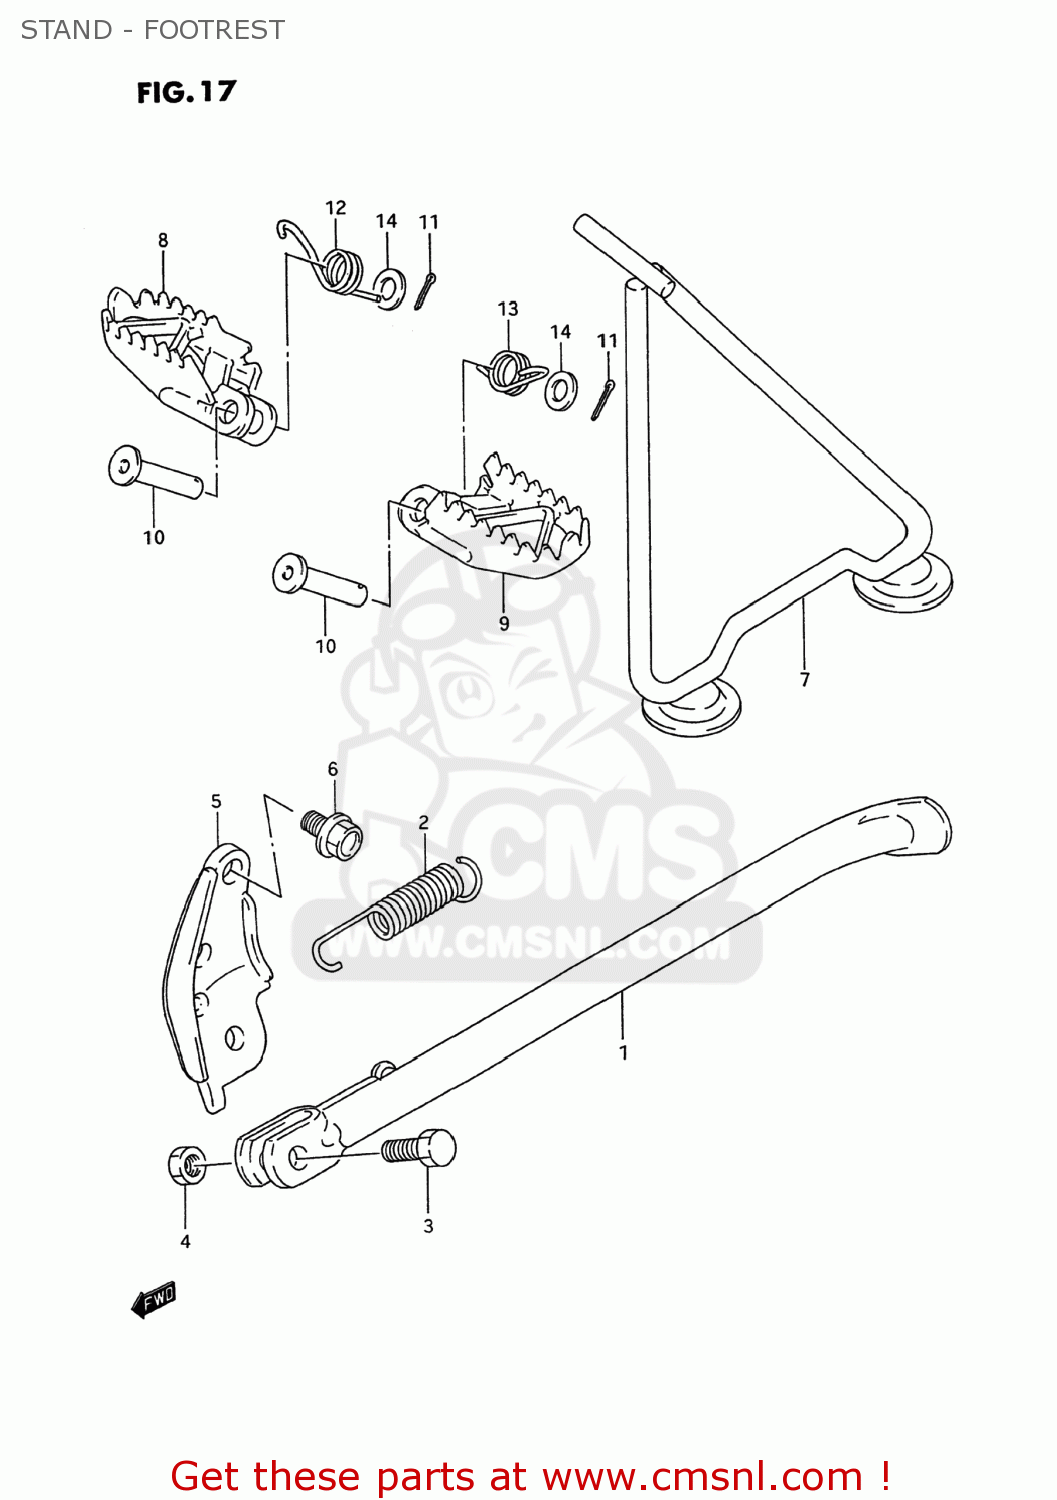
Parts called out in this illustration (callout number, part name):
1	STAND,PROP(BLACK)
2	SPRING
3	BOLT(10X30)
4	NUT
5	BRACKET,PROP STAND(BLACK)
6	BOLT
7	STAND COMP
8	FOOTREST,R
9	FOOTREST,L
10	PIN(10X41.5)
11	PIN 25X20
12	SPRING
13	SPRING
14	WASHER
